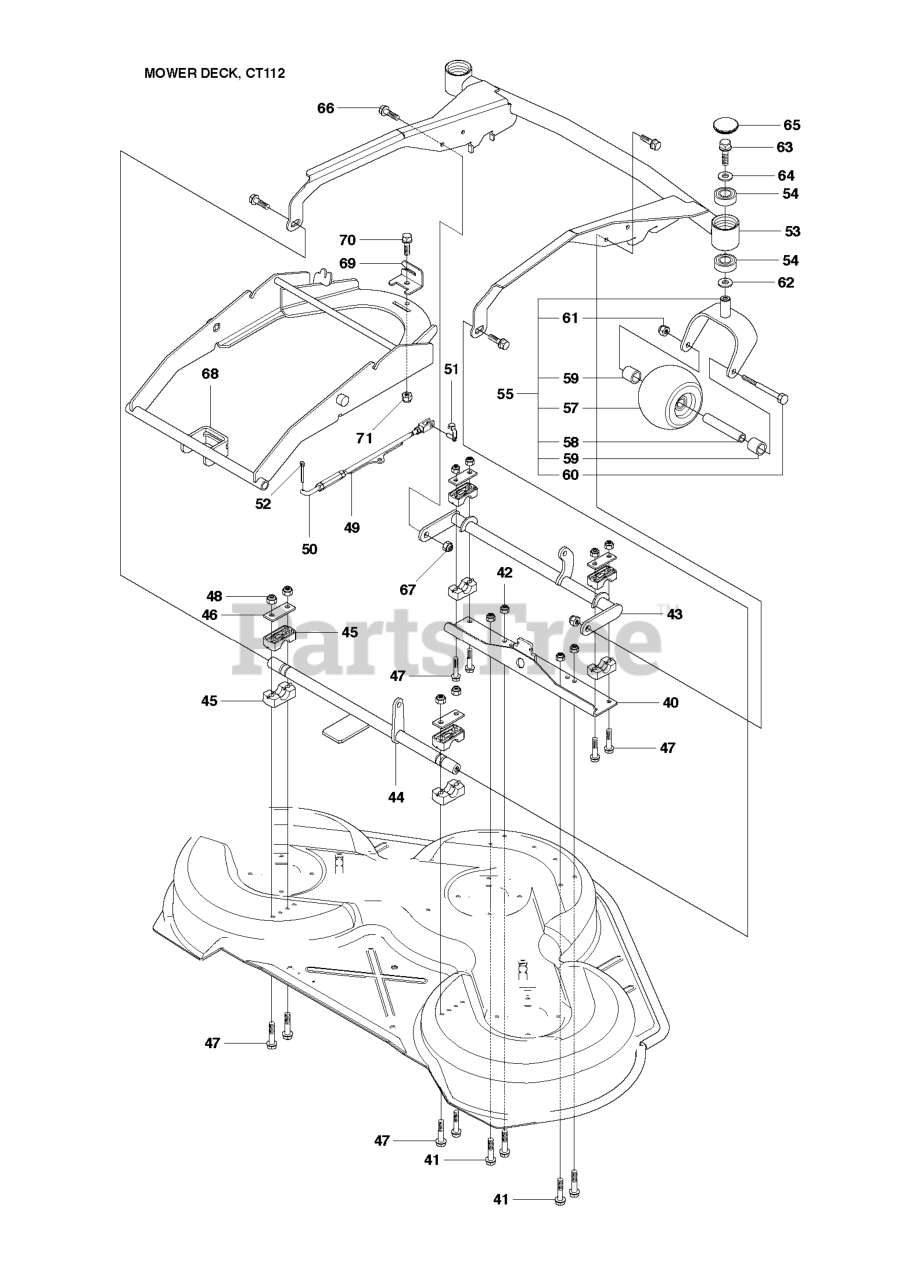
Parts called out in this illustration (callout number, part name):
42	LOCKNUT M8
48	LOCKNUT M8
50	PARALLEL ROD
54	BALL BEARING 6004-2RS1
55	PIVOT WHEELS
57	DECK ROLLER, FRONT
61	NUT
65	HUB CAP PIVOT WHEEL
67	LOCKNUT M8
71	LOCKNUT M8
